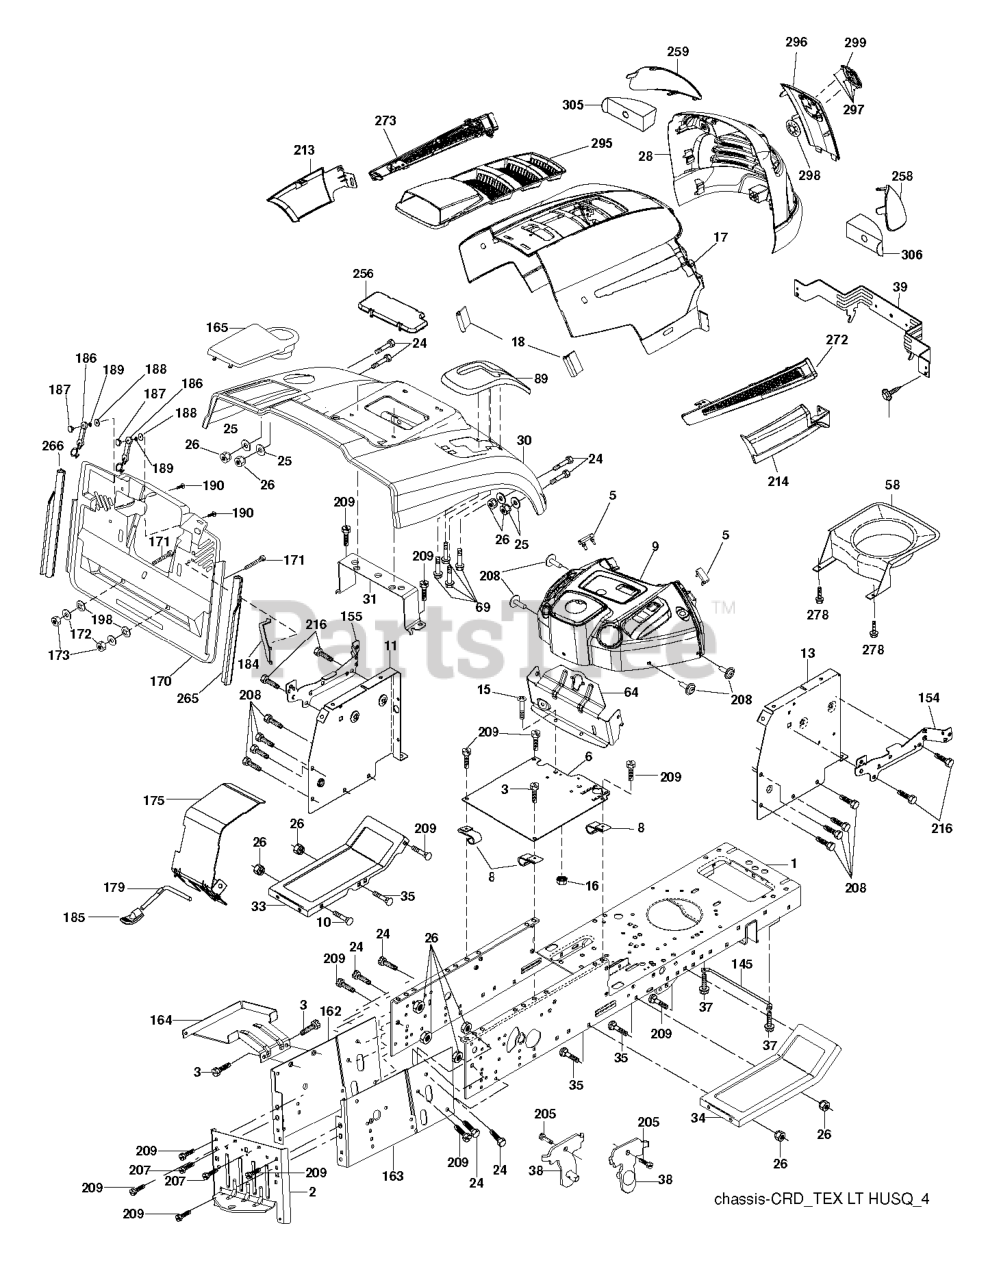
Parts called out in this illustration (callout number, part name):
2	DRAWBAR
3	SCREW 3/8-16X3/4
5	BUMPER DASH
6	PLATE
8	CLIP,INSULATOR
10	BOLT D
11	PANEL.DASH.LH.LTX
13	PANEL ASM, DASH RH
15	Screw, Machine, Truss Head 5/16-18 UNC x 3/4
16	NUT
17	HOOD.HUSQVARNA.LT.ORANGE
18	BUMPER.HOOD.TEX.HUSQVARNA
25	WASHER
26	NUT
28	GRILLE.SVC.HUSQVARNA.LT.GREY
30	CONSOLE.CRD.AUTO.GRY
31	BRACKET SUPPORT FENDER
33	FOOTREST PNT LH
34	FOOTREST PNT RH
37	Screw 5/16-18 x 1/2 Hex, Self Tapping 5/16-18 x 1/2
38	BRACKET ASM PIVOT MOWER REAR
39	BRACKET PIVOT
69	SCREW.HI-LO.CONSOLE
89	CONSOLE.CRD.AUTO.GREY.2005
145	ROD.PIVOT.HOOD
162	BRACKET
163	BRACKET EXTEN CHASSIS RH CRD
165	RP.COVER.BATTERY.CRD.GREY
172	WASHER
175	DOOR TRAP
179	ROD PIVOT FBI
184	BRACKET.ACTUATOR.BAGGER.SRD
186	LATCH ASSY
187	WELDNUT
189	LOCKWASHER #10
190	SCREW
207	SCREW, 5/16-18 X 1/2
208	SCREW 3/8-16X1/2
209	SCREW, 3/8-16X3/4
213	SKIRT SIDE LH
214	SKIRT SIDE RH
216	SCREW HEXWSHR 1/4-20X3/4
256	COVER FENDER CRD
258	LENS.HUSQVARNA LT.RH
259	LENS.HUSQVARNA LT.LH
265	SEALING
266	SEALING
272	VENT SIDE HOOD LH
273	VENT SIDE HOOD RH
278	SCREW.#10 X 0.750.BOS
295	VENT TOP HOOD
296	TRIM
297	CLIP.RETAINER.TINNER.
298	NUT PUSH M
299	RP LOGO
305	INSERT REFLECTIVE
306	INSERT.REFLECTIVE.RH.
